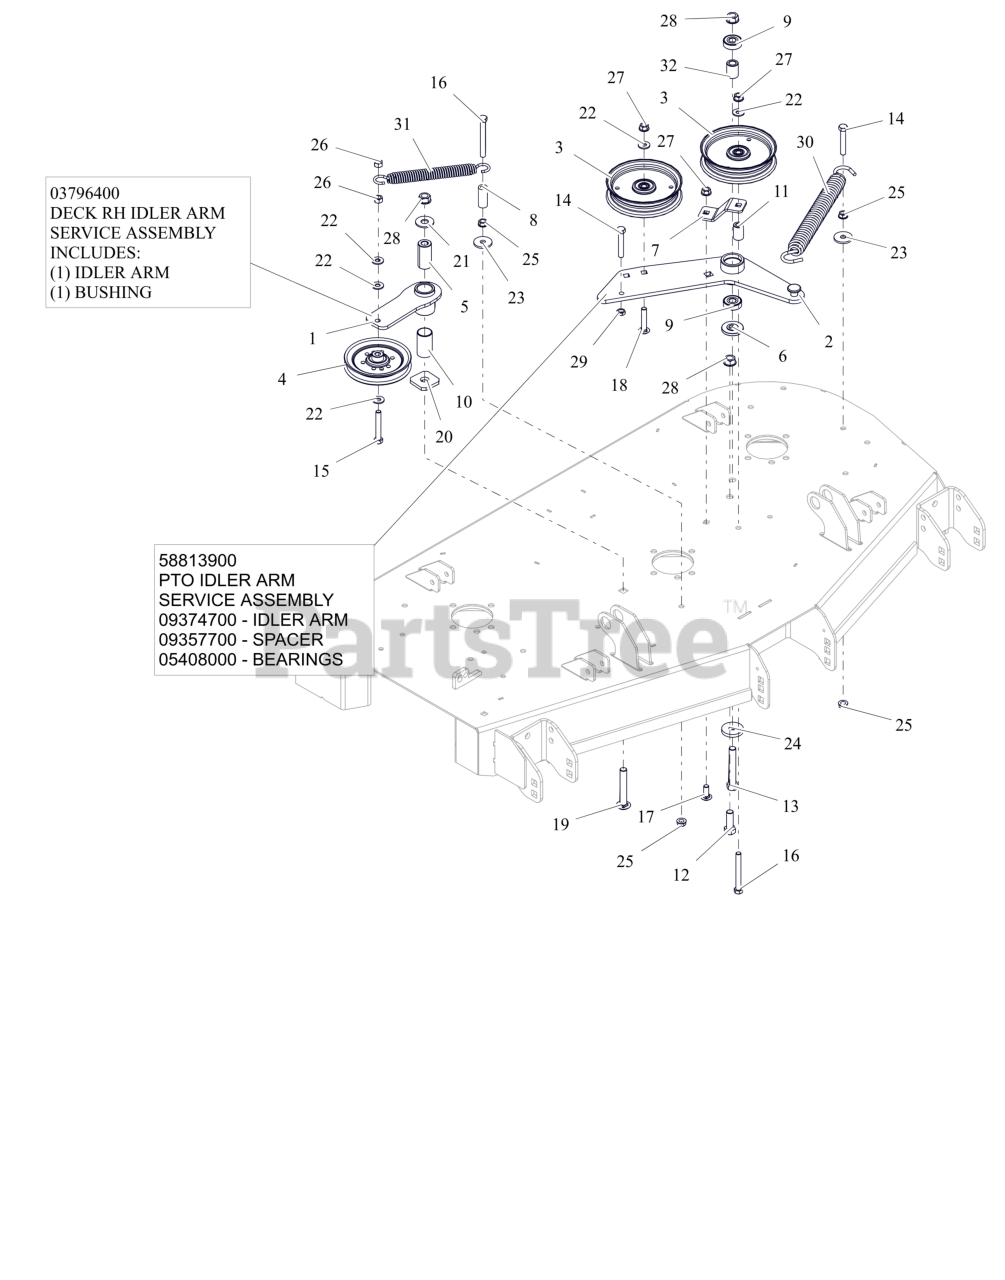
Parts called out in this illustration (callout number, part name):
1	WMT, IDLER ARM - BLACK
1	ASM, IDLER ARM (DECK)
2	WLDMT, IDLER ARM PT660
2	PTO IDLER ARM
3	IDLER- FLAT - 5.00" X .75"
4	IDLER, V, 5.00X.38
5	BSHG, SPCR .502X.997X2.03 PM
6	SPACER, IDLER ARM
7	PTO FIXED IDLER MTG BRKT-ORG
8	HOSE, .38 X 1.65
9	BRG-BALL .500X1.38X.437
10	BSHG, 1.00X1.125X1.937
11	BUSHING, SLV .380X.750X1.190
12	BLT,HEX .50-13X1.50 G5 ZCC
13	BLT,HEX .50-13X3.25 G5 ZCC
14	BLT,HEX .38-16X2.25 G5 ZCC
15	BLT, HEX .38-16X2.50 G5 ZCC
16	BLT, HEX .38-16X3.25 G5 ZCC
17	BLT,RHSSN .38-16X1.00 G5 ZCC
18	BLT,RHSSN.375-16X2.00 G5 ZCC
19	BTL,RHSSN .500-13 X 3.25 G5 ZCC
20	WSHR-FLT .640X1.75X.250
21	WSHR,FLT .563X1.375X.109 ZCC
22	WSHR,FLT .375X.875X.083 ZCC
23	WSHR,FLT .406X1.375X.135 ZCC
24	WSHR-FL-STL 0.557X1.625X0.25 ZCC
25	NUT, SPNLK-FLG .38-16 G5 ZCC
26	NUT-LK-CTR .38-16 ZC120
27	NUT-LK-CTR-FLG .375-16 GF ZCC
28	NUT-LK-CTR-FLG .500-13 GG ZCC
29	NUT-JAM .375-16 G2 ZCC
30	SPRING, EXTENSION
31	SPRING- EXTENSION
32	SPACER .510 X .867 X 1.1485
